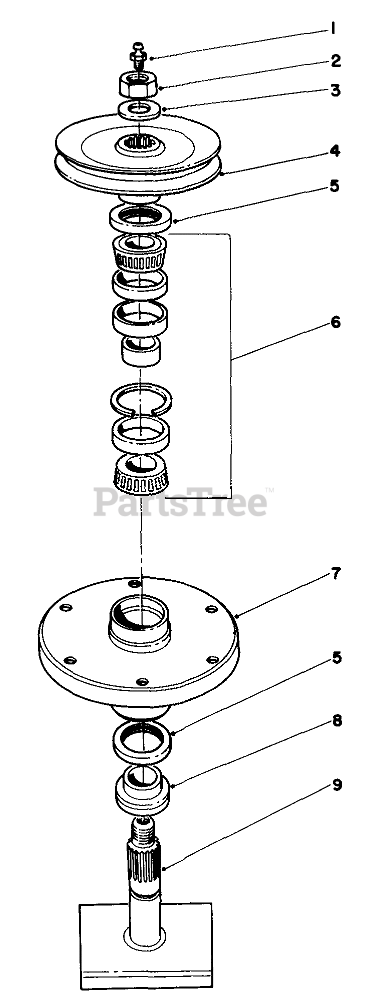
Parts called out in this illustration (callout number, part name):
1	FITTING-GREASE
2	NUT-HEX
3	WASHER
4	PULLEY AND HUB ASM
5	SEAL-OIL
6	BEARING ASM
7	HOUSING-SPINDLE
8	SPACER
9	SHAFT
